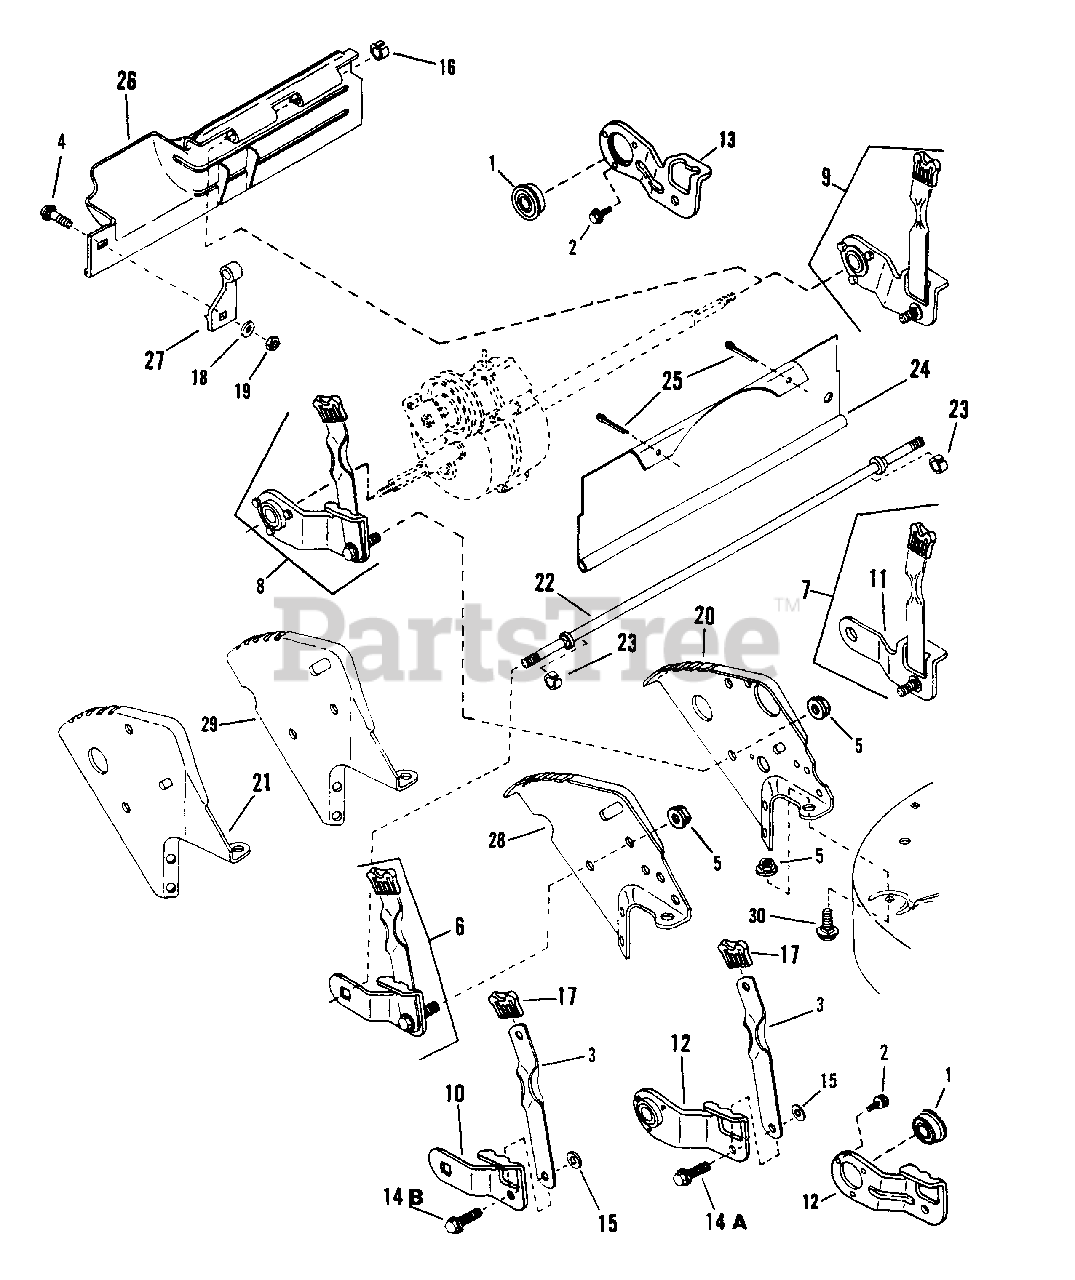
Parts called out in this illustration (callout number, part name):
1	BEARING
2	SCREW, #10-32 x 3/8" Self-Tapping
3	LATCH, Height Adjusting
4	BOLT, 1/4-20 x 1/2" Short Neck Carriage (Gr. 5)
5	NUT, 5/16-18 Hex Flange Lock
6	ASSEMBLY, Wheel Arm (Square Hole, Front Left & Rear Right)
7	ASSEMBLY, Wheel Arm (Round Hole, Front Right & Rear Left)
8	ASSEMBLY, Wheel Arm
9	ASSEMBLY, Wheel Arm
10	ARM, (Square Axle End)
11	ARM, (Round Axle End)
12	ARM, Wheel Rear Right
13	ARM, Wheel Rear Left
14A	BOLT, 5/16-18 x 1" Shoulder
14B	BOLT, 5/16-18 x 3/4" Shoulder
15	RETAINER, 5/16 Bolt
16	RING
17	GRIP, Latch
18	WASHER, 1/4 Internal Tooth Lock
19	NUT, 1/4-20 Hex
20	BRACKET, Right Rear Wheel
21	BRACKET, Left Rear Wheel
22	AXLE,
23	RING
24	GUARD, Rear Foot
25	PIN, 1/8 x 1-1/2" Cotter
26	GUARD, Rear Foot
27	SUPPORT, Foot Guard
28	BRACKET, Right Rear Wheel
29	BRACKET, Left Rear Wheel
30	BOLT, 5/16-18 x 3/4" Short Neck Carriage
